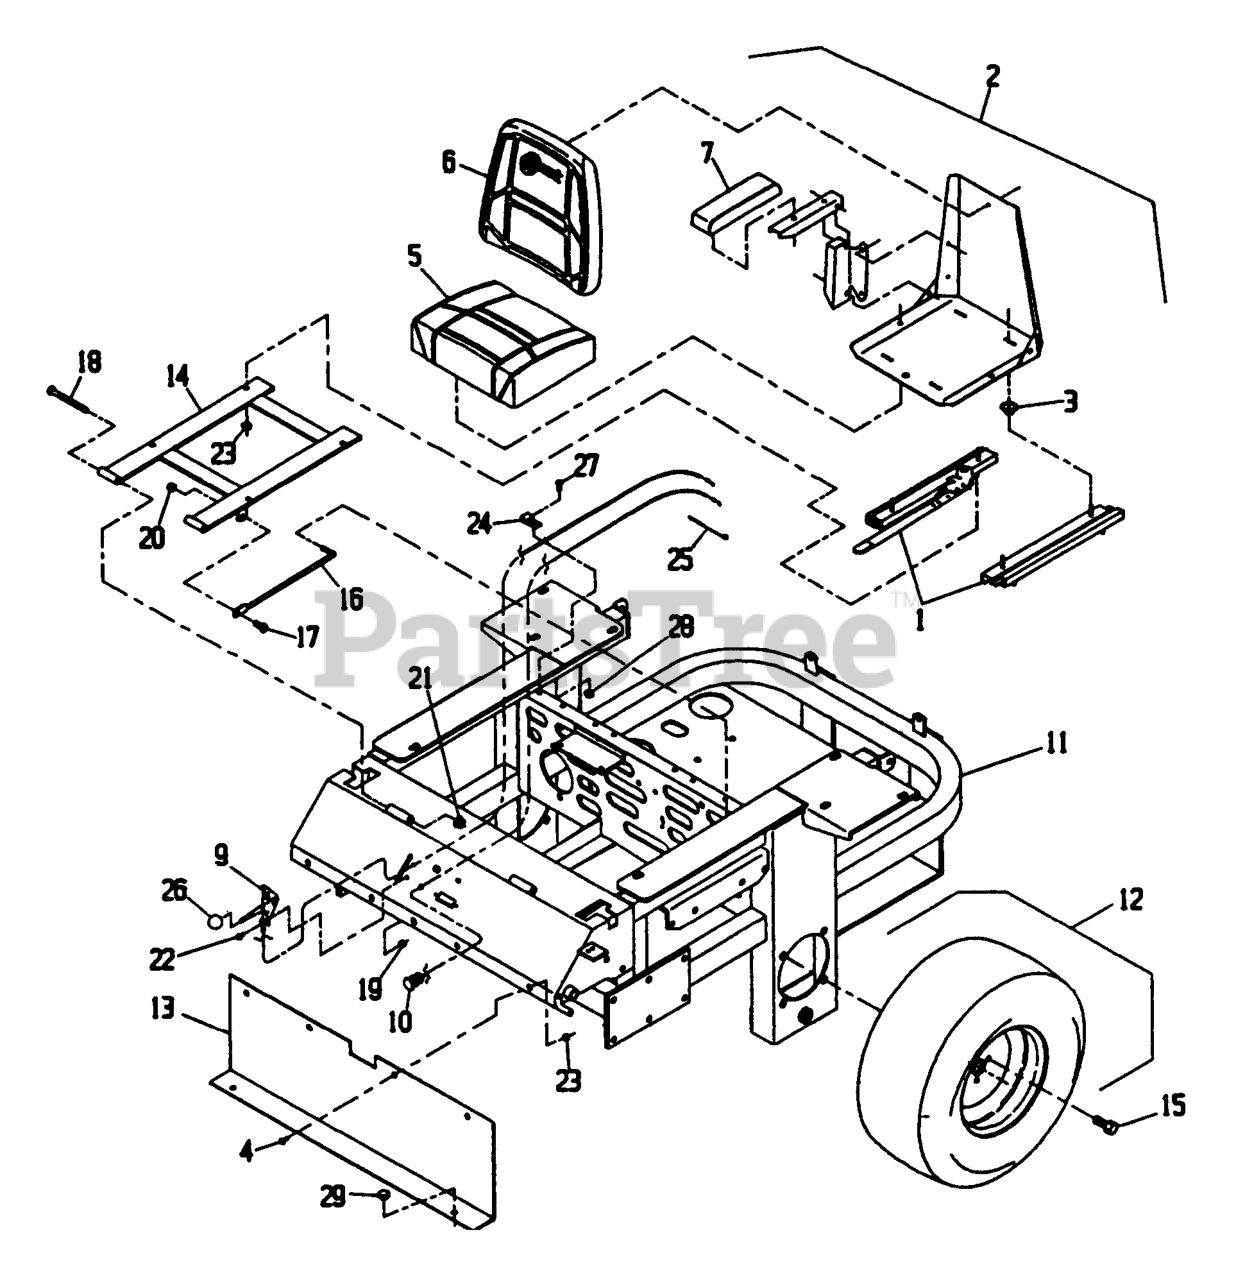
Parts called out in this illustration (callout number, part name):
3	SPACER-TRACK
10	CONTROL-CHOKE
15	WHEEL BOLT
16	ROD-HOLDUP, SEAT
22	BOLT-CARR
24	CLIP-LOOM
25	TIE-PLASTIC
26	KNOB-BALL
